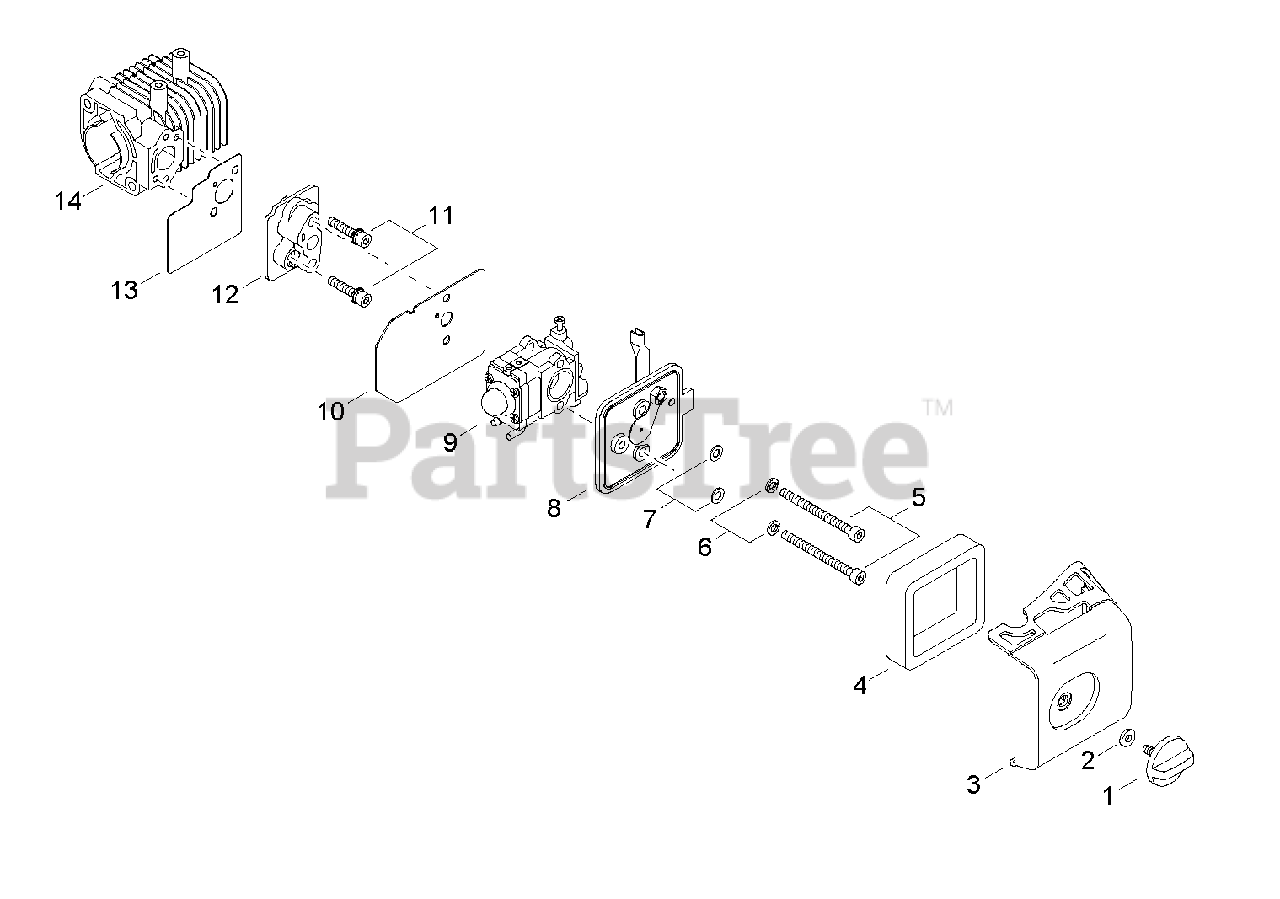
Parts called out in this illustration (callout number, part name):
1	THUMBSCREW
2	WASHER - VINYL
3	COVER, AIR FILTER
4	FILTER, AIR
5	SCREW - 5X55
6	LOCKWASHER - 5
7	WASHER - 5
8	AIR FILTER CASE ASSY
9	CARBURETOR WYJ-488
10	GASKET, INTAKE
11	SCREW - 5X30
12	INSULATOR, INTAKE
13	GASKET, INTAKE
14	CYLINDER
